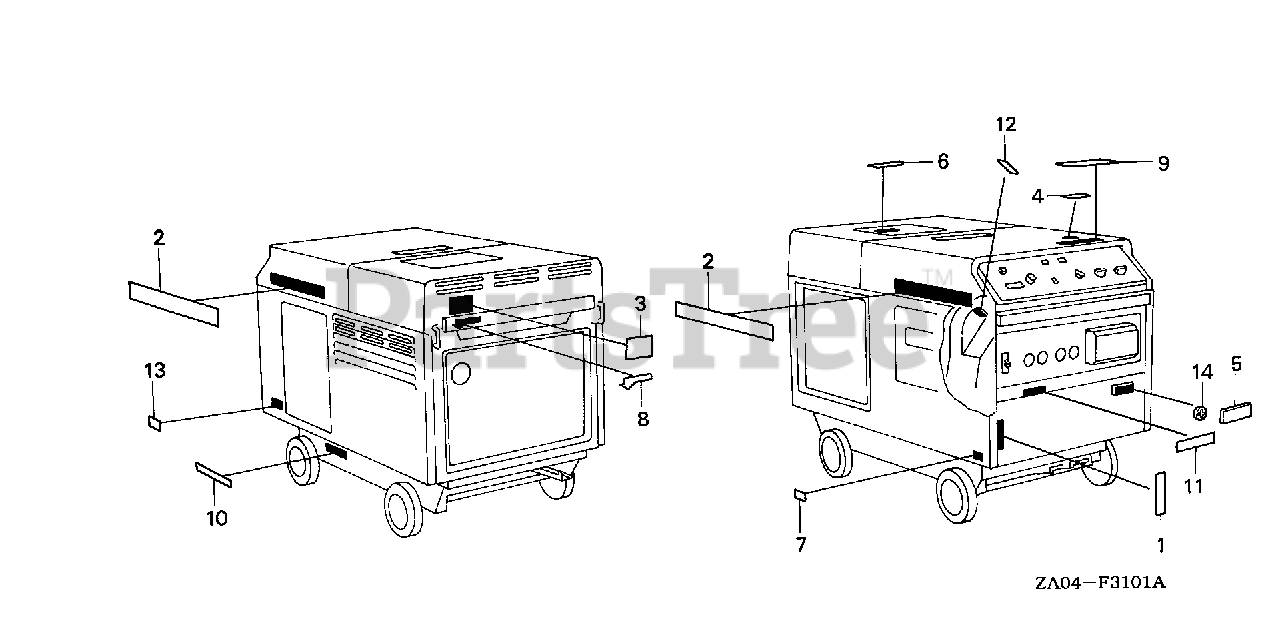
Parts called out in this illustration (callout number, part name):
3	MARK, SPECIFICATION
5	EMBLEM (LIQUID COOLED ENGINE)
7	MARK, GROUND
8	MARK, EX. CAUTION
9	LABEL, OPERATOR WARNING (E)
10	MARK, DRAIN
13	MARK, OIL CAUTION
14	NUT, SPEED (3MM)
